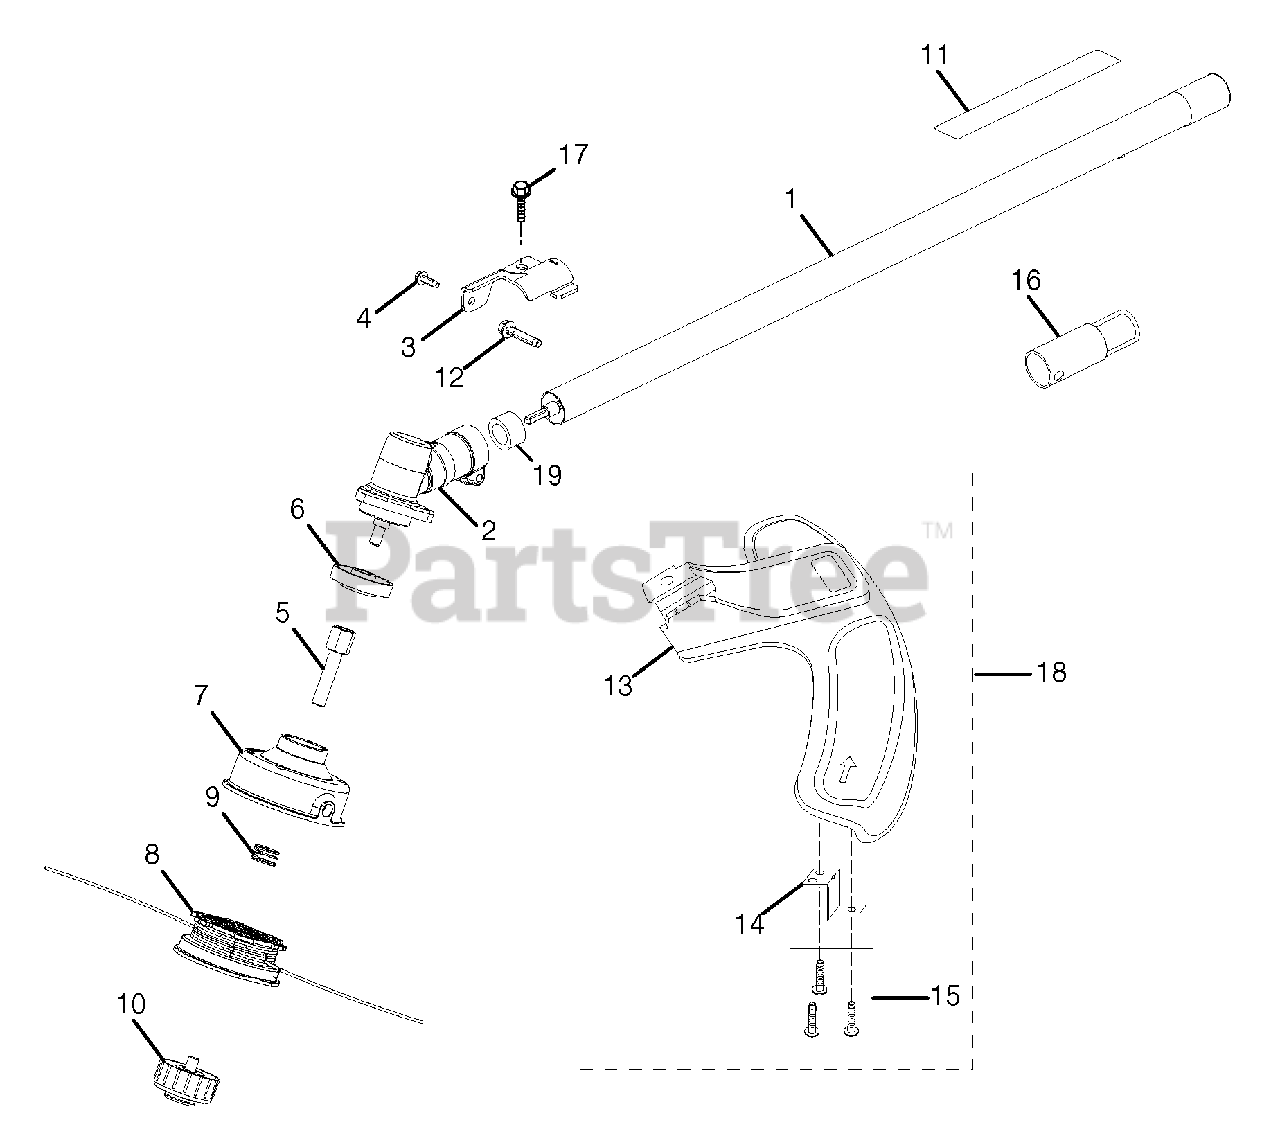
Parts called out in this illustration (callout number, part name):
1	Straight Shaft Assembly
2	Gear Case Assembly
3	Grass Deflector Clamp
4	Screw (#10-24 X 5/8 in. Hex Washer Head, Tri-lobular)
5	Trimmer Head Shaft Adaptor
6	Flanged Washer
7	Trimmer Head
8	Spool with Line (.095)
9	Compression Spring
10	Retaining Cap, Left-handed threads
11	Warning Label
12	Screw (#1/4-20 x 1-1/4 in. Hex Washer Head, Tri-lobular)
13	Grass Deflector
14	Line Cutting Blade
15	Screw (#8-16 x 1/2 in. Truss Head, Tri-lobular)
16	Storage Cap
17	Screw (#1/4-20 x 1-1/4 in. Hex Washer Head, Machine)
18	Grass Deflector Assembly
19	Spacer
